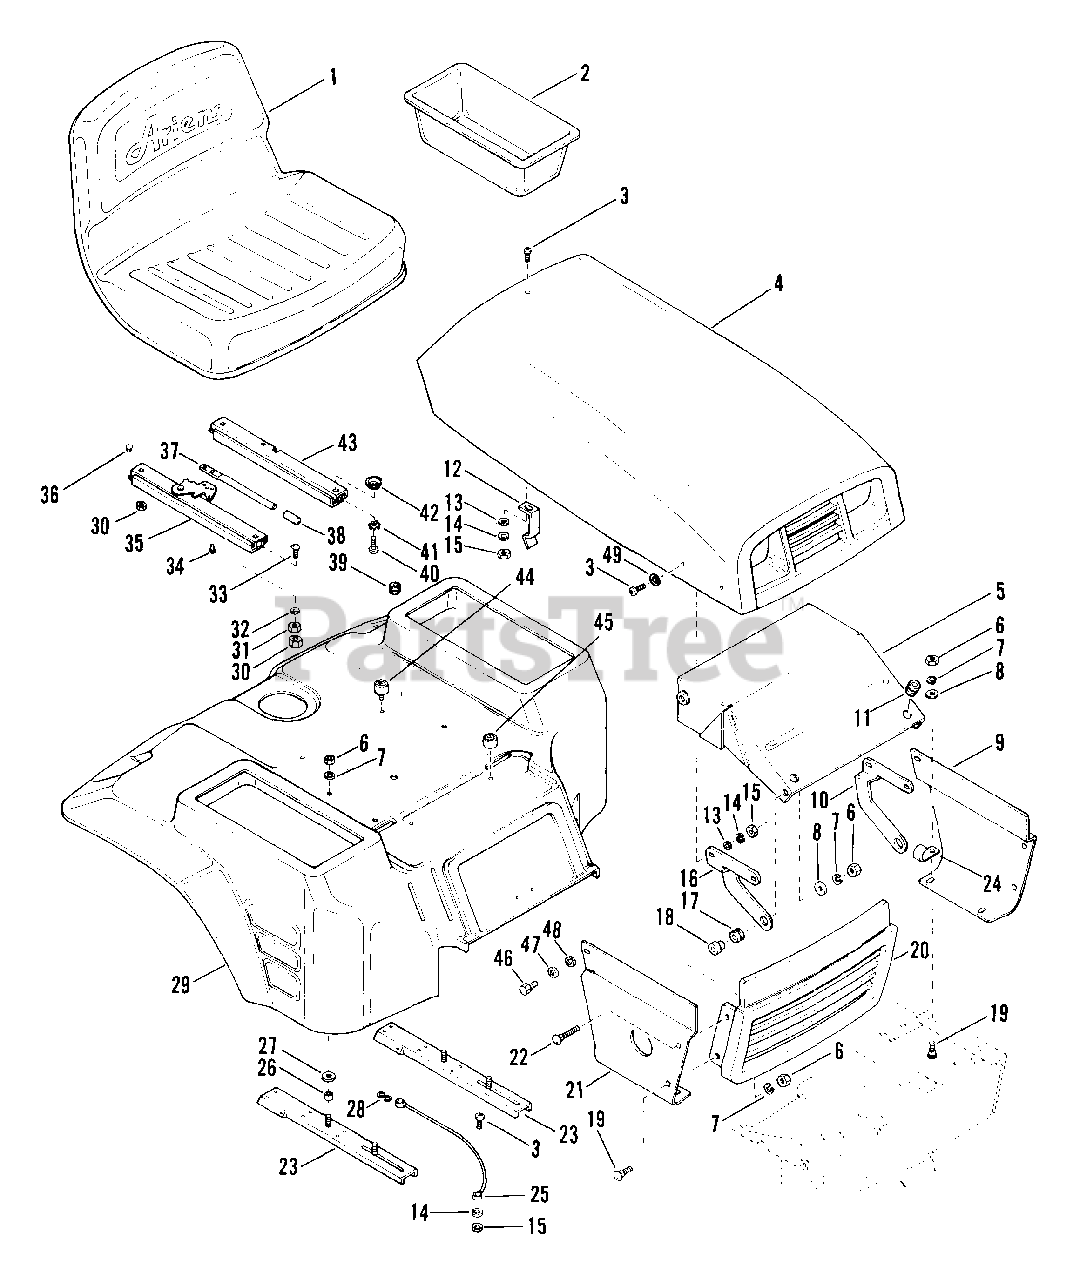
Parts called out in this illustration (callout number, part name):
1	SEAT
3	SCR .25-20X.75 TS PH PL
4	HOOD & GRILL
5	MUFFLER SHIELD
6	NUT-HEX .375-16
7	WSHR-LK .375X.094 MED PL
8	WSHR-FL-STL .438X1.0X.083 PL
9	SIDE SHEET L.H.
10	L.H. HOOD HINGE
11	GROMMET .438ID X .688 OD
12	HOOD STOP
13	WSHR-FL-STL.281X.62X.065 PL
14	WSHR-LK .250X.077 HVY PL
15	NUT-HEX .250-20 PL
16	R.H. HOOD HINGE
17	GROMMET .50IDX.812OD
18	SPACER -FLANGED .390X.500X.781
19	BLT-RDHDSQSHNK .38-16X1.00 PL
21	SIDE SHEET R. H.
21	SIDE SHEET
22	BLT-RDHDSQNK .38-16X2.00 SHTYW
23	SEAT SUPPORT
24	J-CLAMP
26	SPACER .380X.503X.281
27	WSHR-FL-STL .390X.750X.125 PL
29	REAR DECK
30	NUT-LK .312-18 GR A PL
31	NUT-HEX .312-18
32	WSHR-LK .312X.097 PL HVY
33	SCR-CAP BTHD.31-18X.875 GR5 PK
34	RVT-POP.187X.562 DOME ST
35	SEAT SLIDE R H
36	SCR-CAP BTHD.31-18X.50 GR5 YZ
37	SEAT SLIDE HANDLE
39	GROMMET
40	SCR-MCH .31-18X1.00 CRRH PL
41	WSHR-LK-EXT .313X.030 PL
42	SEAT SLIDE SPACER
43	SEAT SLIDE L H
44	ISOLATOR,SEAT REAR
45	ISOLATOR,SEAT FRONT
46	SCR-MCH .31-18X.75 TSKBHD PL
47	WSHR-FL-STL.344X.688X.065PL
48	WSHR-LK-INT .313X.030 PL
49	WSHR-FL-STL .250X.562X.049 PL
